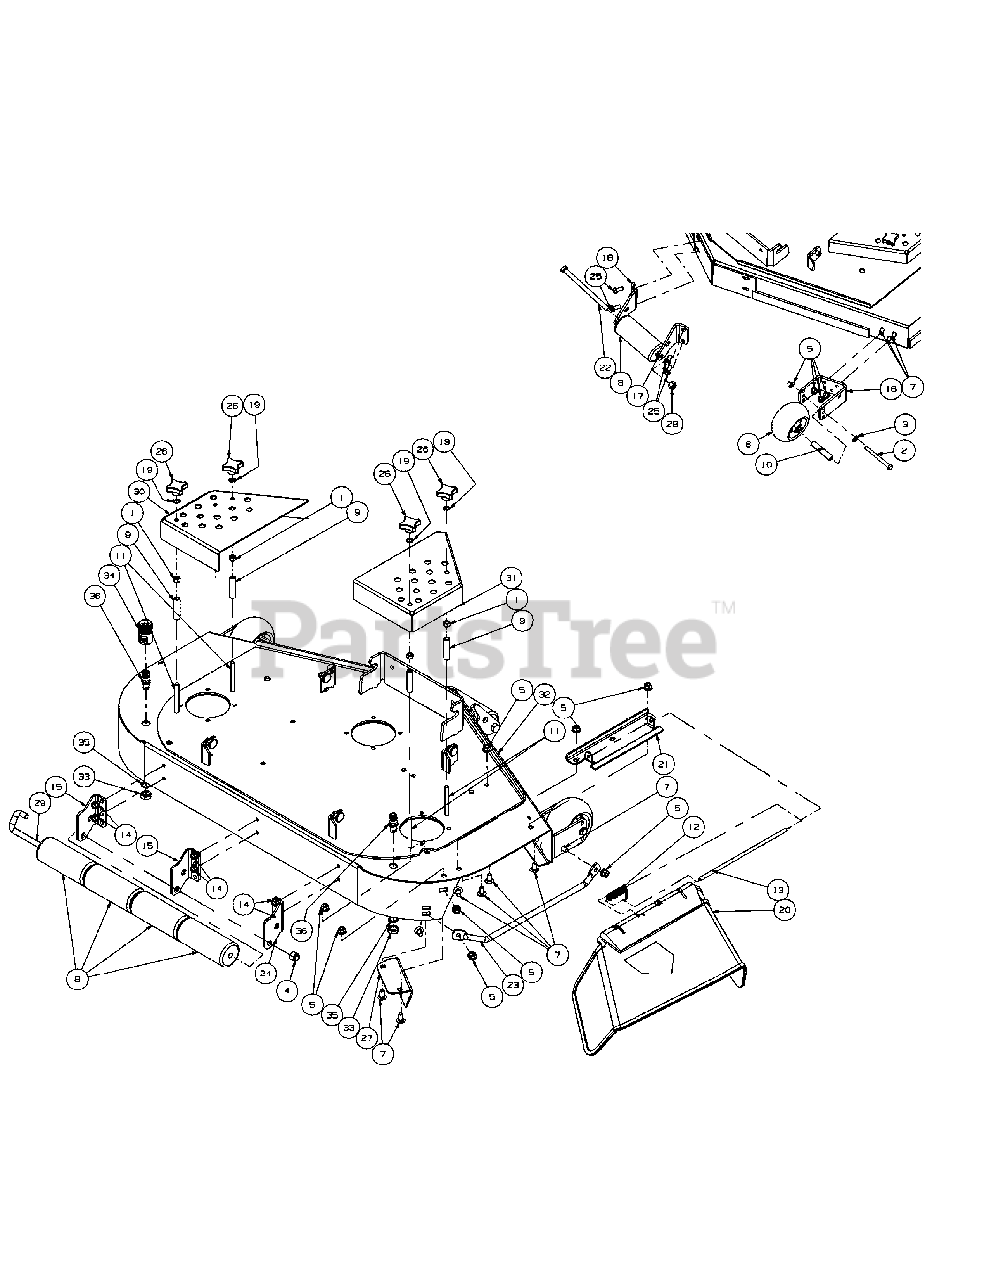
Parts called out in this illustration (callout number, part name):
1	Hex Nut 3/8-16
2	Hex Cap Screw, 3/8-16, 3.75
4	Hex Nut, 1/2-13, Insert Lock
5	Hex Nut, 3/8-16 Flange Lock
6	Complete Wheel, 5.00 Dia
7	Carriage Bolt 3/8-16 x .75
8	Front Roller
9	Spacer Stop Deck
10	Wheel Spacer
11	Carriage Bolt, 3/8-16 x 3.5 Lg
12	Torsion Spring
13	Chute Deflector Rod
14	Self Tapping Screw, 5/16-18 x 1/2
19	External Washer, 3/8
20	Deflector Chute
21	Deflector Chute Bracket
22	Hex Cap Screw, 1/2-20 x 7.50
23	Fabricated Deck Finger Guard
25	Self Tapping Screw, 3/8-16 x 0.875
26	Plastic Knob
27	Fabricated Deck, Chute Bracket
28	Lock Nut, Nylon Insert, 1/2-20
29	J-Hook w/ Threaded Roller
32	44 Fabricated Deck Assembly
33	Hex Nut, M16-1.5
34	Water Nozzle Adaptor
35	Lock Washer, 17 x 23.8 x 1.95
36	Deck Water Nozzle
